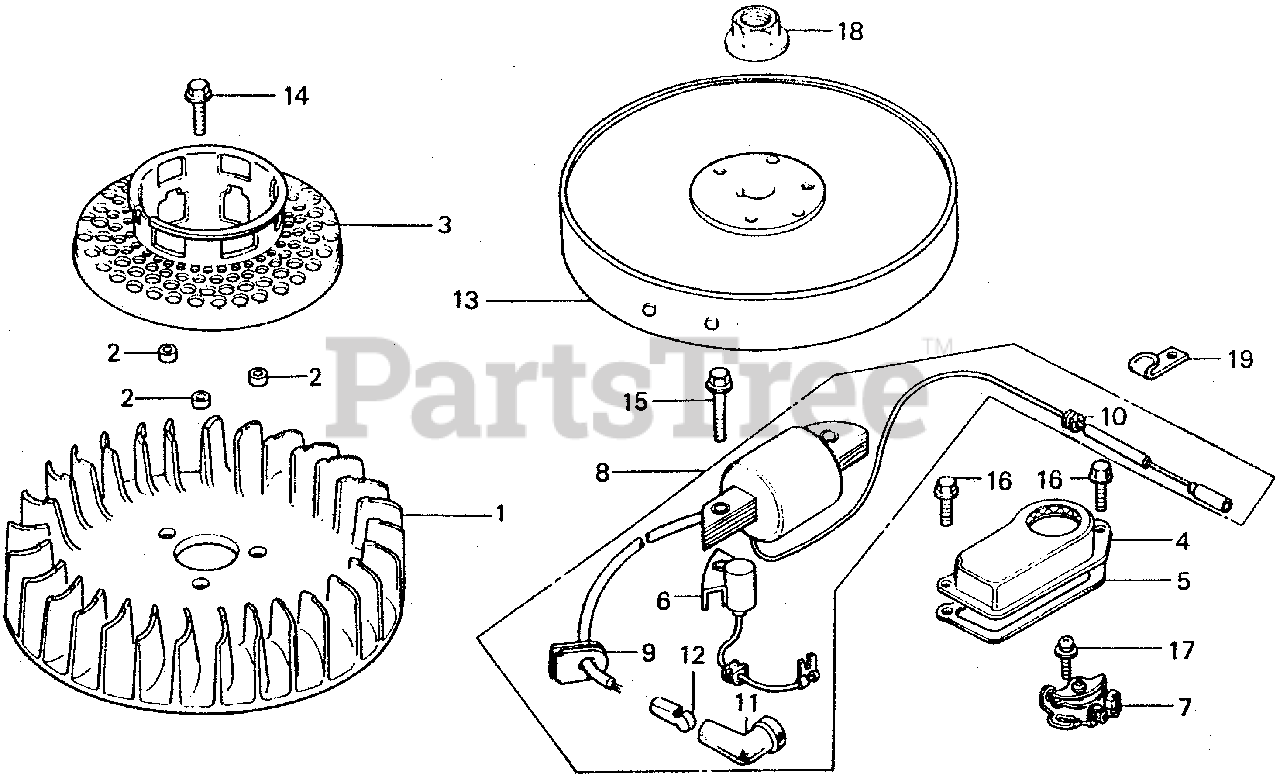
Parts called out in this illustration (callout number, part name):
1	FAN, COOLING
2	COLLAR, FAN
3	PULLEY, STARTER
4	COVER, BREAKER
5	GASKET, BREAKER COVER (NOT AVAILABLE)
7	POINTS ASSY.
8	COIL ASSY., IGNITION
8	COIL ASSY., IGNITION (NOT AVAILABLE)
9	GROMMET, WIRE
10	GROMMET, PRIMARY WIRE (NOT AVAILABLE)
11	CAP, IGNITION
11	CAP, IGNITION (TOYO)
12	TERMINAL, PLUG
13	FLYWHEEL (POINT)
14	BOLT, FLANGE (6X16)
15	BOLT, FLANGE (6X32) (CT200)
16	BOLT, FLANGE (5X10)
17	SCREW-WASHER (5X12)
18	NUT, SPECIAL (14MM)
19	CLIP, WIRE
